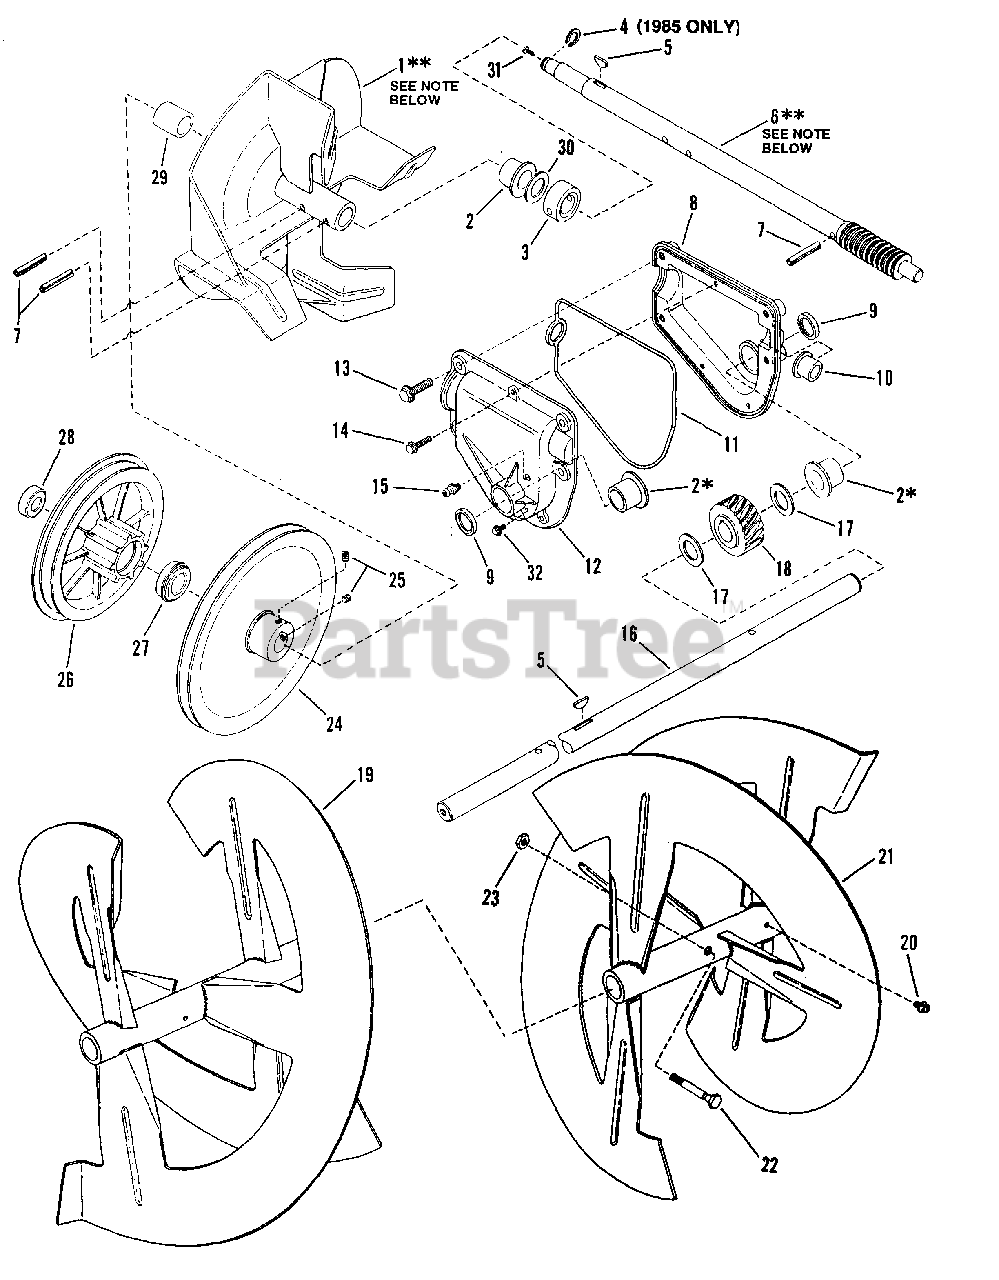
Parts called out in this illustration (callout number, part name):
1	IMPELLER (Fan)
2	BEARING
3	COLLAR
4	RING, Retaining (1985 Models)
5	KEY, #9 Woodruff
6	SHAFT, Worm (1985 Models)
7	ROLL-PIN, 1/4 x 1-1/4
8	COVER, Gear Case (L.H.)
10	BUSHING
11	"O" RING
12	COVER, Gear Case (R.H.)
13	SCREW, 1/4 - 20 x 3/4", Self-Tapping
14	SCREW, #10 - 24 x 5/8", Self-Tapping
15	FITTING, Lube
16	SHAFT, Auger
17	WASHER, Thrust
18	GEAR, Worm
19	AUGER, Right Hand
20	LUBE FITTING, Straight (press-fit for .187 dia. Hole)
21	AUGER, Right Hand
22	PIN, Shear, .248 ID. X 1.75 LG
23	COTTER PIN, .094 X 0.750 BLK
24	PULLEY, 8.36" O.D.
25	SCREW, 5/16 - 18 Hex Socket Set
26	DRIVE PLATE ASSY.
27	BEARING, Ball
28	BEARING, Ball
29	SPACER
30	WASHER, Thrust
31	SCREW, 1/4 - 20 x 1/2", Self-Tapping, Truss Hd.
32	SCREW, #10-24 x 1/2" Hex Washer Self-Tap (Torx)
